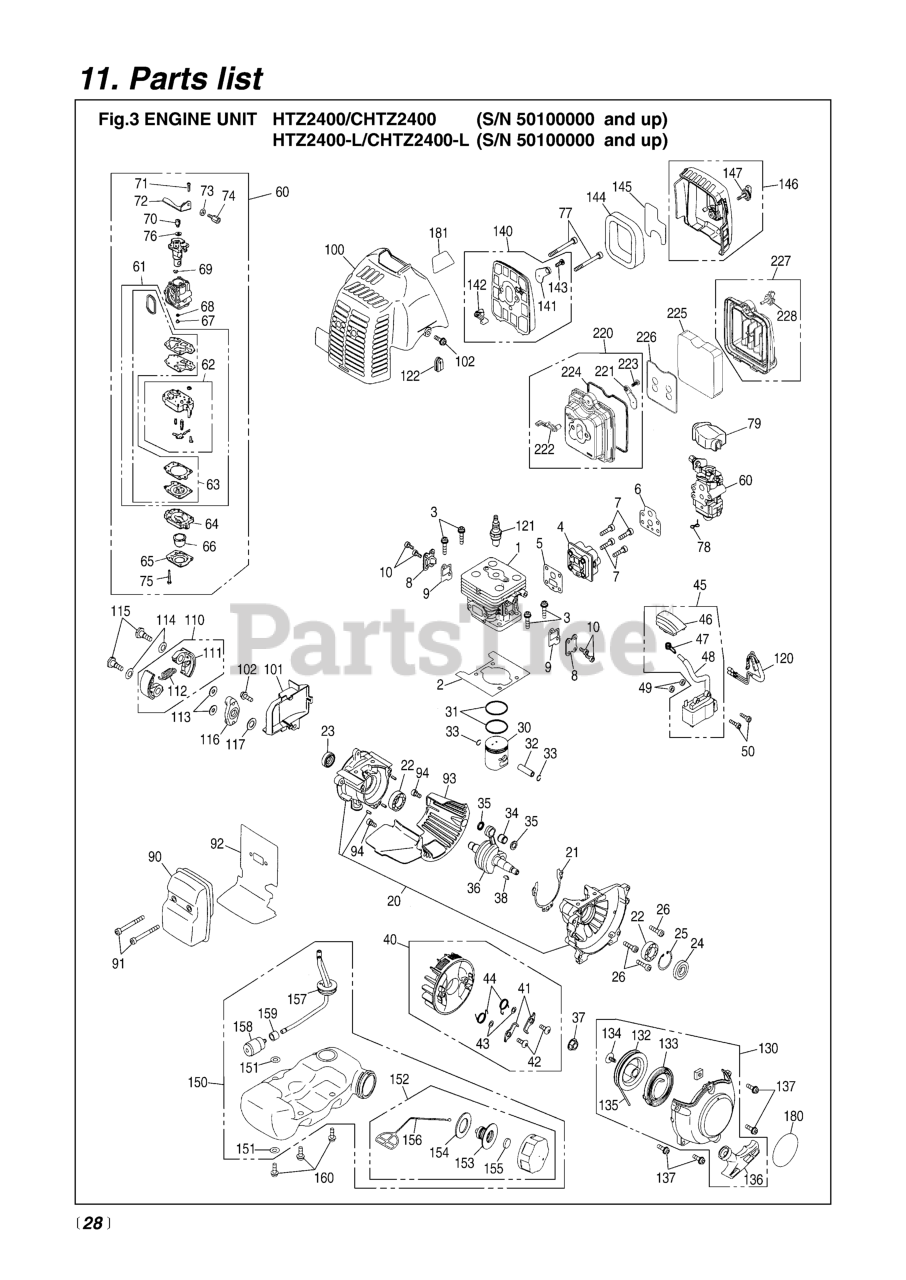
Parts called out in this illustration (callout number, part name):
1	CYLINDER
2	GASKET,BASE
3	BOLT
4	INSULATOR
5	GASKET, INSULATOR
6	GASKET, CARB.
7	BOLT, TORX
8	COVER, TR
9	GASKET, TR
10	BOLT, TORX
20	CRANKCASE-C
21	GASKET, CASE
22	BEARING
23	SEAL
24	SEAL, OIL (RPLS 1140-21220)
25	RING, SNAP, M28 x 1.2
26	BOLT (RPLS 2850-14220)
30	PISTON (RPLS T1551-41110)
31	RING, PISTON
32	PIN, PISTON
33	RING, SNAP (RPLS 1101-41320)
34	BEARING
35	WASHER
38	KEY
40	ROTOR (RPLS -7111)
41	PAWL
42	SCREW
43	WASHER
44	SPRING
45	COIL-A
46	CAP (RPLS 4810-72110)
47	SPRING
49	SPACER (RPLS -71260)
50	BOLT TORX
60	CARBURETOR-A
61	REBUILD KIT
62	BODY, PUMP
63	KIT, GASKET (REPLACES-06020)
64	BODY, PURGE
65	COVER, PUMP
66	PUMP, PRIMING
67	JET
68	RING, O
69	RING
70	SWIVEL
71	SCREW
73	NUT, CABLE ADJUSTER
74	SCREW, CABLE ADJUSTER
75	SCREW
76	WASHER
77	BOLT
78	CLIP
79	COVER
90	MUFFLER
91	BOLT
92	GASKET, MUFFLER
94	BOLT
100	COVER,ENGINE
101	DEFLECTOR
102	BOLT, TORX
110	SHOE-C
111	SHOE
112	SPRING
113	WASHER, FLAT (USE 182303)
116	PLATE,CLUTCH
117	WASHER
122	GROMMET
130	RECOIL-A
132	REEL
133	SPRING, SPIRAL
134	SCREW (RPLS -75150)
135	ROPE
136	KNOB (RPLS -75420)
137	BOLT, TORX
140	BODY-A
141	PLATE, CHOKE
143	SCREW
144	ELEMENT
145	SCREEN
146	COVER ASSEMBLY
147	KNOB (RPLS -82220)
150	TANK-A
151	PACKING
152	CAP ASSY (RPLS -85201)
153	HOLDER (REPLACES -85230)
154	PACKING
155	FILTER
156	STOPPER
157	PIPE-C
158	FILTER ASSY
160	BOLT, TORX
180	LABEL,RECOIL
181	LABEL, COVER
220	BODY ASSY
221	PLATE, CHOKE
222	LEVER
223	SCREW
224	PACKING
225	ELEMENT
227	COVER A (RPLS. T1513-82200)
228	KNOB
